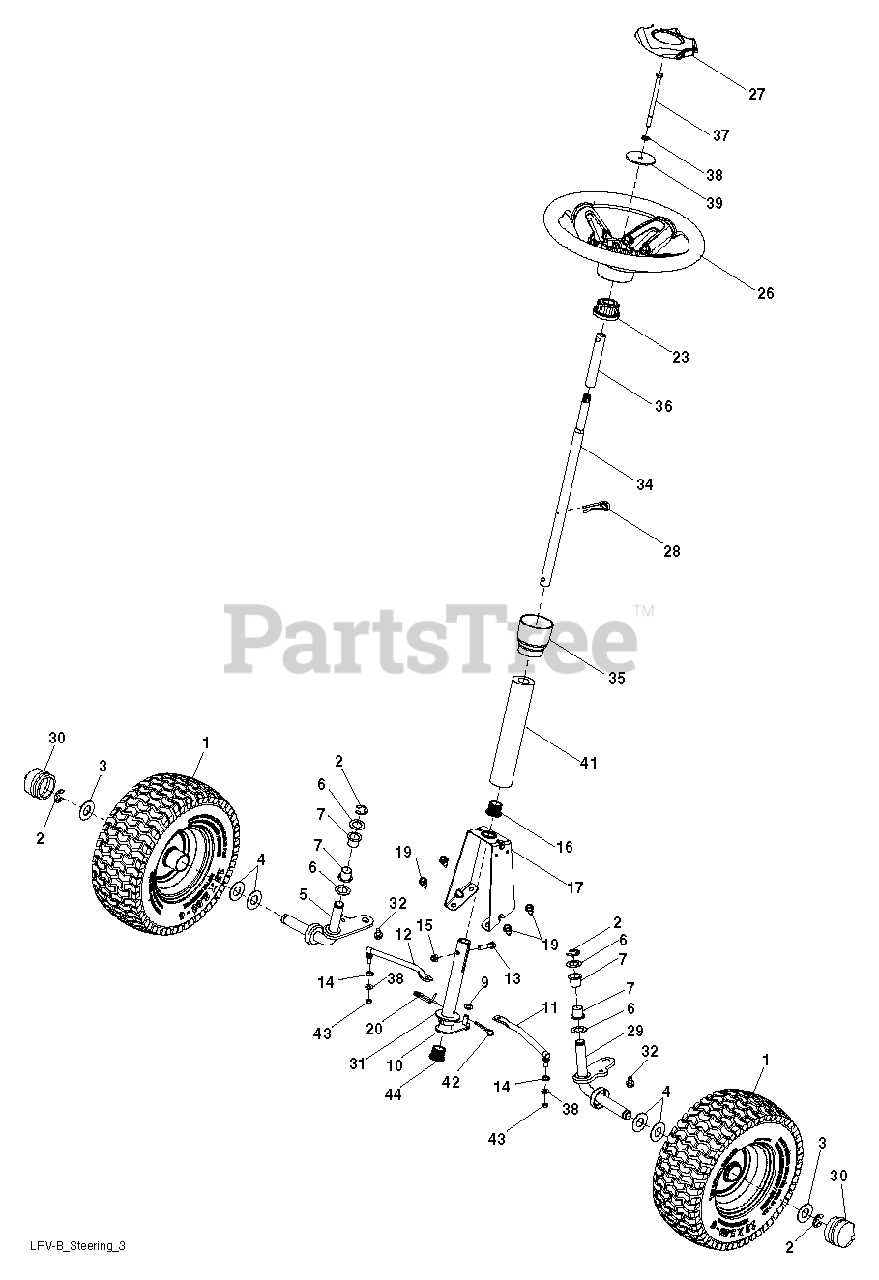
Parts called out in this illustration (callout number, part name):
1	WHEEL.TUBE.13X5.00-6.YELLOW
2	E-RING LT
3	WASHER.HARDENED
5	WELDMENT.SPINDLE.RH.LRV2
7	Steering Column Bearing
10	WELDMENT, LWR STRG SHAFT
11	SUBASM.LINKS.STEERING.LH.LRV2
12	SUBASM.LINK.STEERING.RH.LRV2
13	HEX BOLT
14	WASHER M
15	NUT.71038.31-18.HEX.NYLOCK
16	BUSHING, STEERING SNAP
17	SUPPORT.STEERING.UPPER.LRV2
19	SCREW
20	CLIP.SPRING.STEERINGG
23	STEERING.WHEEL.ADAPTER
26	WHEEL.STEERING.MLT.BR.YEL/OVRM
27	CAP.WHL.STRNG.STDSRRD.SRS.YELL
28	RETAINER.CLIP.SPRING.S
29	WELDMENT.SPINDLE.LH.LRV2
30	CAP.AXLE.FRONT.YELLOW
32	Bolt, 5/16-18 X 1.25
34	SHAFT.STEERING.UPPER.LRV2
35	BOOT.LOWER.STEERING.WHEEL.LRVB
36	SHAFT EXTENSION STEERING
37	BOLT.FIN.HEX.5/16-18
38	LOCKWASHER
39	WASHER.11/32
41	FOAM.SHAFT.STEERING
42	PIN.COTTER.5/64X3/4
43	NUT, CROWNLOCK
44	BUSHING, STEERING SNAP
